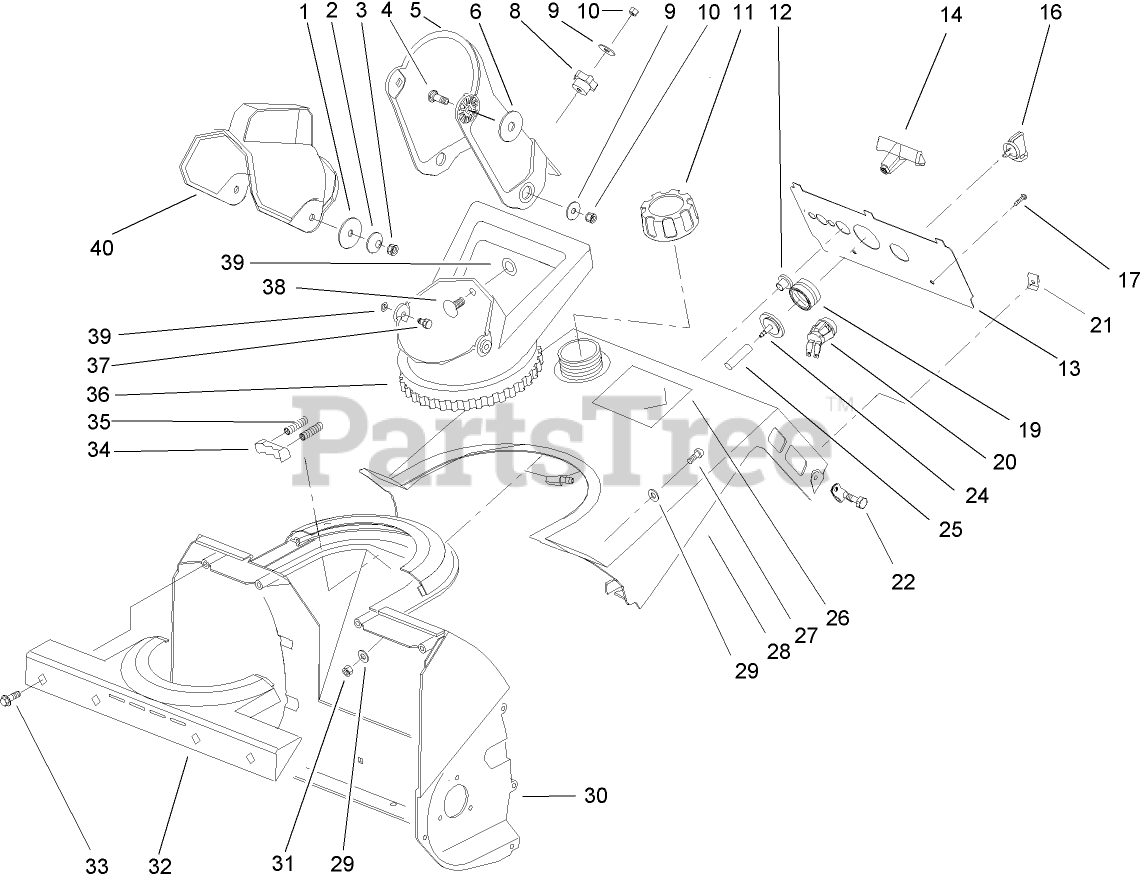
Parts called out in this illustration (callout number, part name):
1	WASHER-FLAT
2	WASHER-BELLEVILLE
3	NUT-LOCK, NI
4	BOLT-CARR
6	WASHER-RUBBER
8	KNOB-CHUTE
9	WASHER-FLAT
10	NUT-LOCK, NI
11	GAS CAP ASM
12	GUIDE-ROPE, STARTER
14	HANDLE-STARTER
16	KEY-IGNITION
17	SCREW-SHWH, THREAD FORMING
19	BULB-PRIMER
20	SWITCH
22	SCREW-THREAD FORMING
24	BODY-PRIMER
25	HOSE-PRIMER
26	DECAL-ELECTRIC START
27	SCREW-PPH
28	SHROUD-TANK, GAS UPPER
29	WASHER-FLAT
30	HOUSING
31	NUT-LOCK, NI
32	RETAINER-CHUTE
33	SCREW-PLASTIC
34	DETENT-CHUTE
35	SPRING-COMPRESSION
36	HANDLE-CHUTE
37	SCREW-HH
38	SCREW-CARR
39	PUSHNUT-RETAINER, BOLT
40	DEFLECTOR-CHUTE
